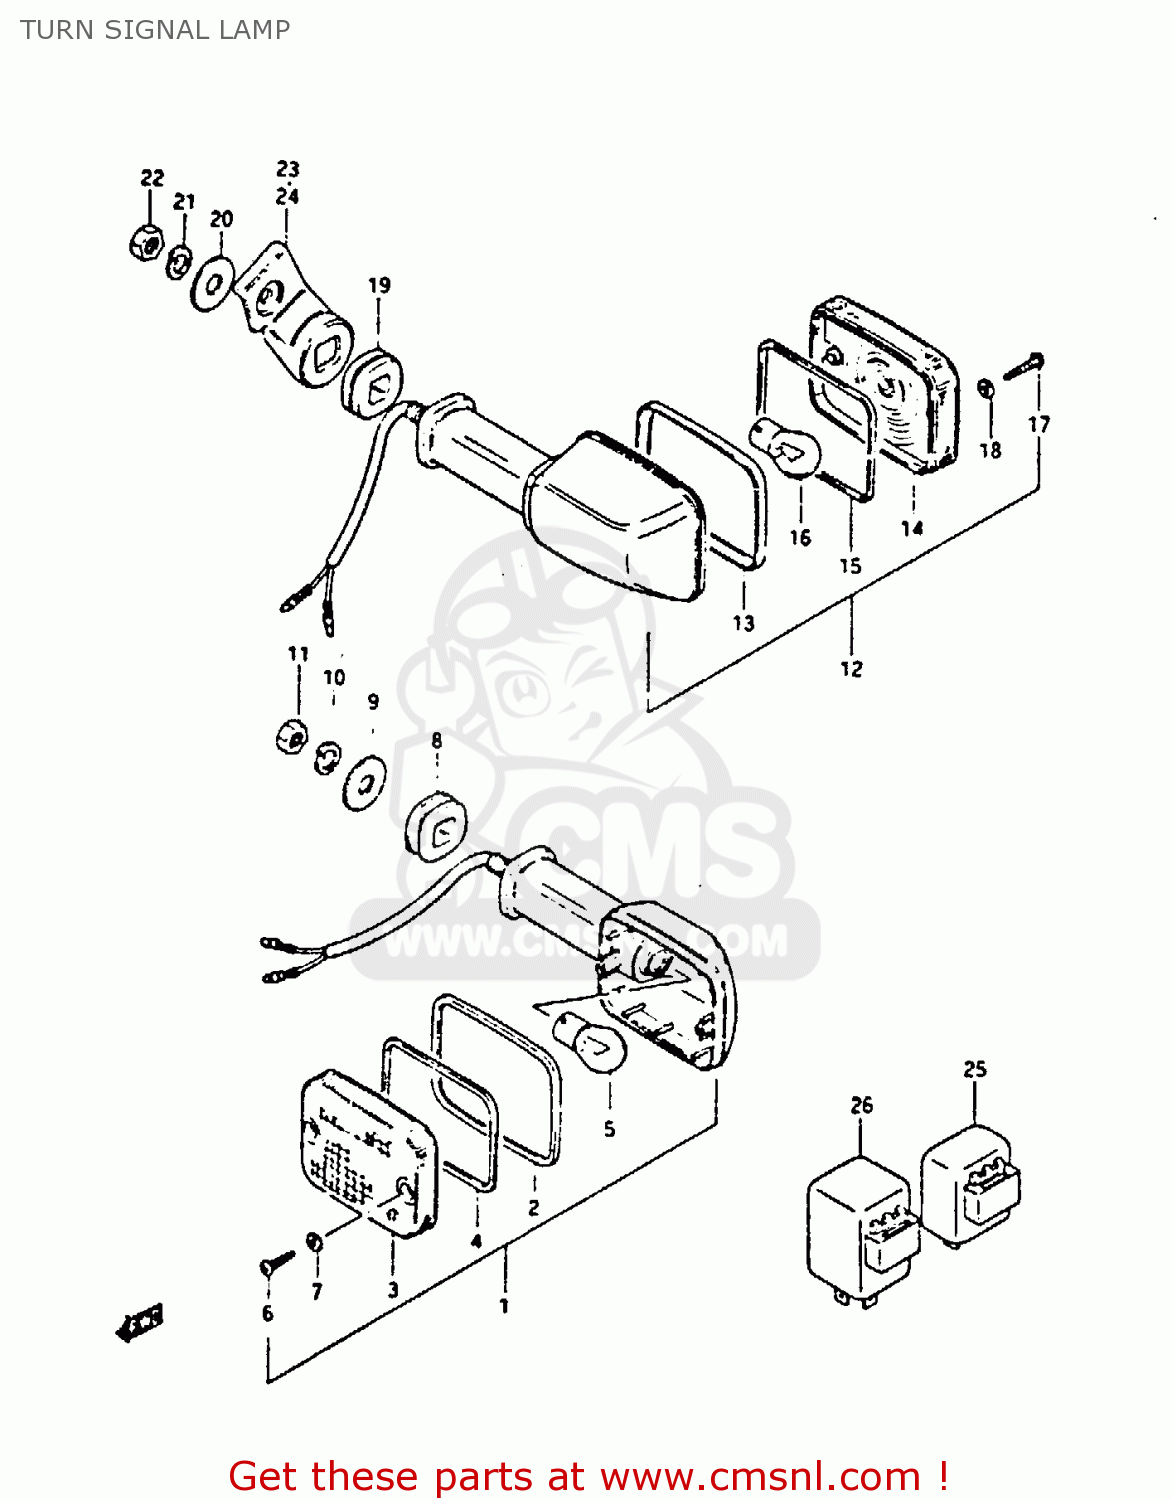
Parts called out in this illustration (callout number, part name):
1	LAMP ASSY,FR T
2	RIM
3	LENS
4	GASKET (NAS)
5	BULB(12V21W)
6	SCREW
7	GASKET (NAS)
8	CUSHION
9	WASHER (10.5X30X2.3)
10	LOCK WASHER
11	NUT
12	LAMP ASSY,RR T
13	RIM
14	LENS
15	GASKET (NAS)
16	BULB(12V21W)
17	SCREW
18	GASKET (NAS)
19	CUSHION
20	WASHER (10.5X30X2.3)
21	LOCK WASHER
22	NUT
23	BRACKET,REAR TURN SIGNAL
24	BRACKET,REAR TURN SIGNAL
25	RELAY ASSEMBLY,TURN SIGNAL
26	RELAY ASSY,TUR
